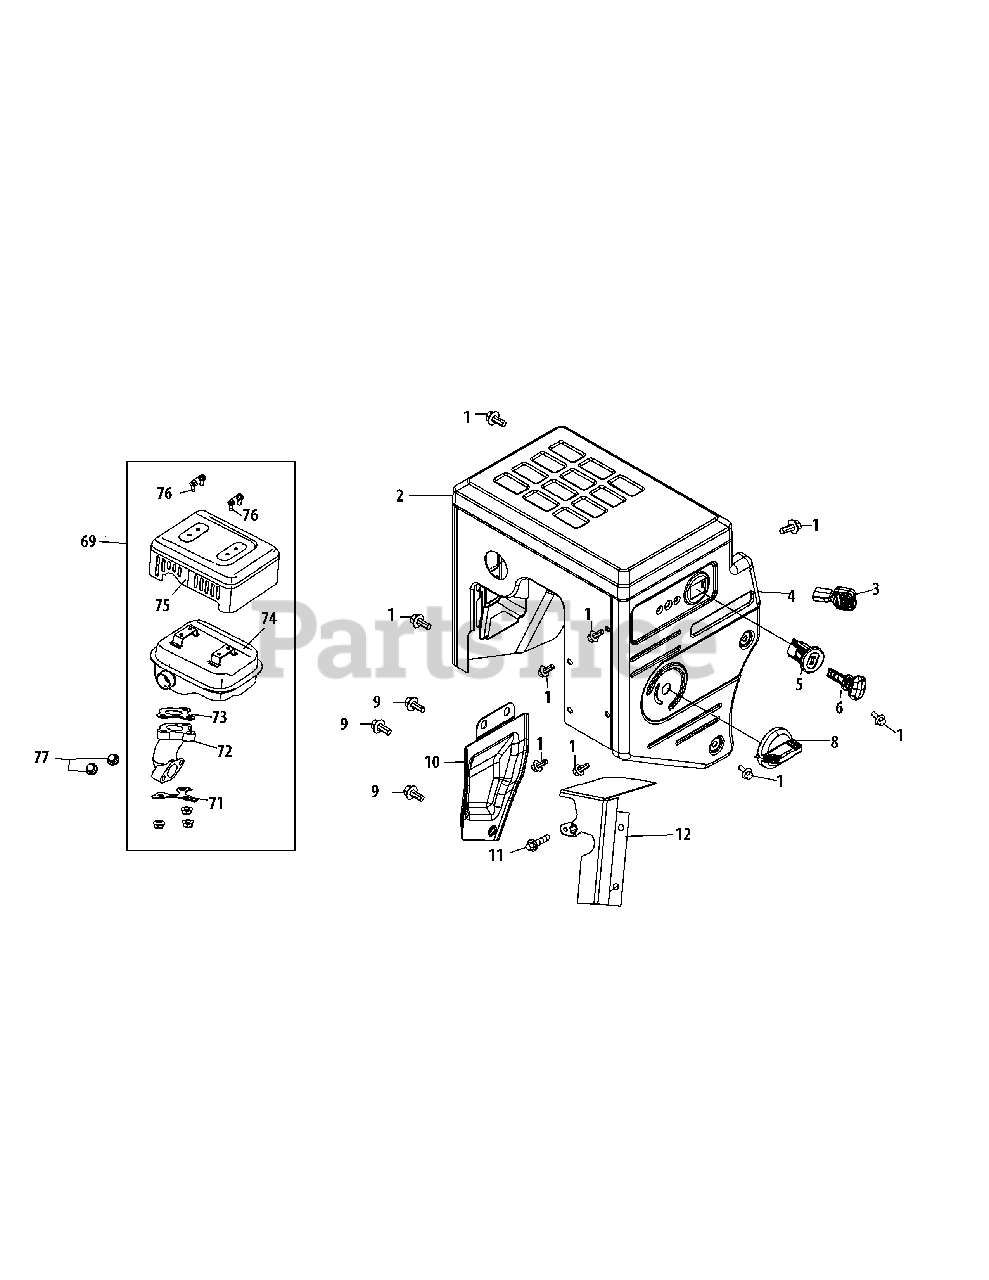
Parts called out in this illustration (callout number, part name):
1	BOLT M6×12
2	MUFFLER SHIELD
3	THROTTLE CONTROL KNOB
4	CONTROL PANEL
5	ENGINE SWITCH BASE
8	CHOKE KNOB
9	BOLT M6×10
10	EXHAUST PIPE SHIELD
11	BOLT M6×16
12	CARB ISOLATOR BRACKET
69	MUFFLER ASSEMBLY
72	EXHAUST PIPE
73	GASKET, MUFFLER
74	MUFFLER BODY
75	MUFFLER GUARD
